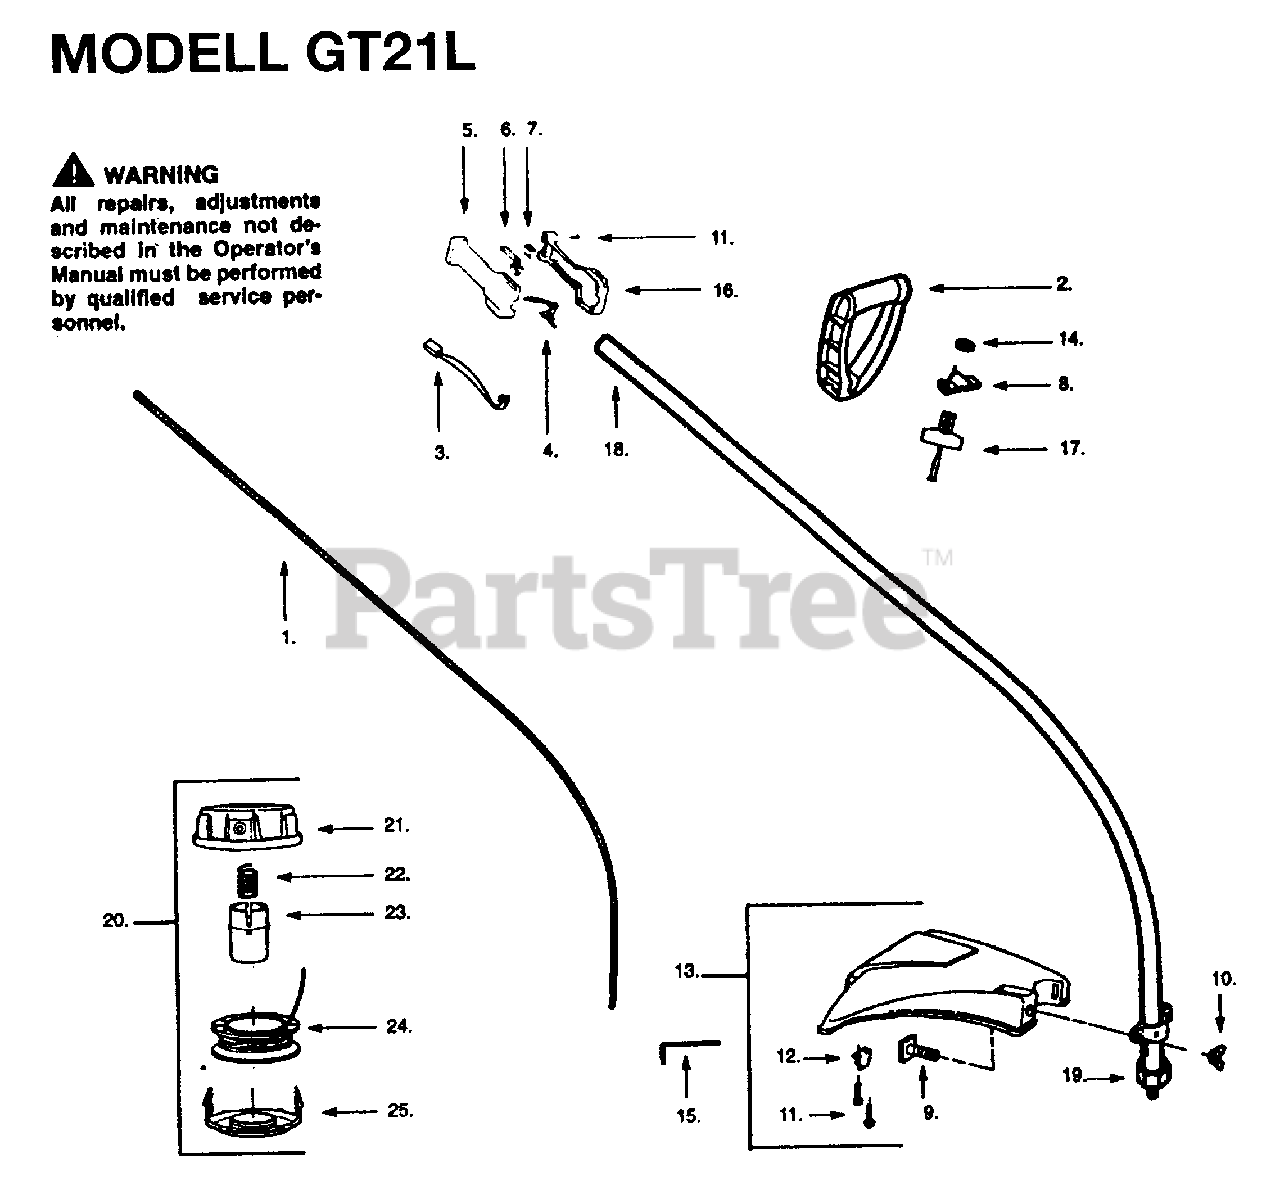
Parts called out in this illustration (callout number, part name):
2	"D" HANDLE
4	THROTTLE TRIGGER
7	REPL BY 530 06 95-72
8	CLAMP-ASSIST HANDLE
9	BOLT, TYPE 2
10	NUT - HANDLE/SHIELD
11	SCREW-10-14 X 13/16 (PL
12	REPL BY 530 09 52-49
14	NUT (1/4-20)
15	ALLEN KEY
17	KIT "T" HANDLE
18	DRIVE SHAFT
20	CUTTING HEAD ASSEMBLY
21	HUB AND SHAFT ASSY
24	SPOOL W/ LINE NLA
